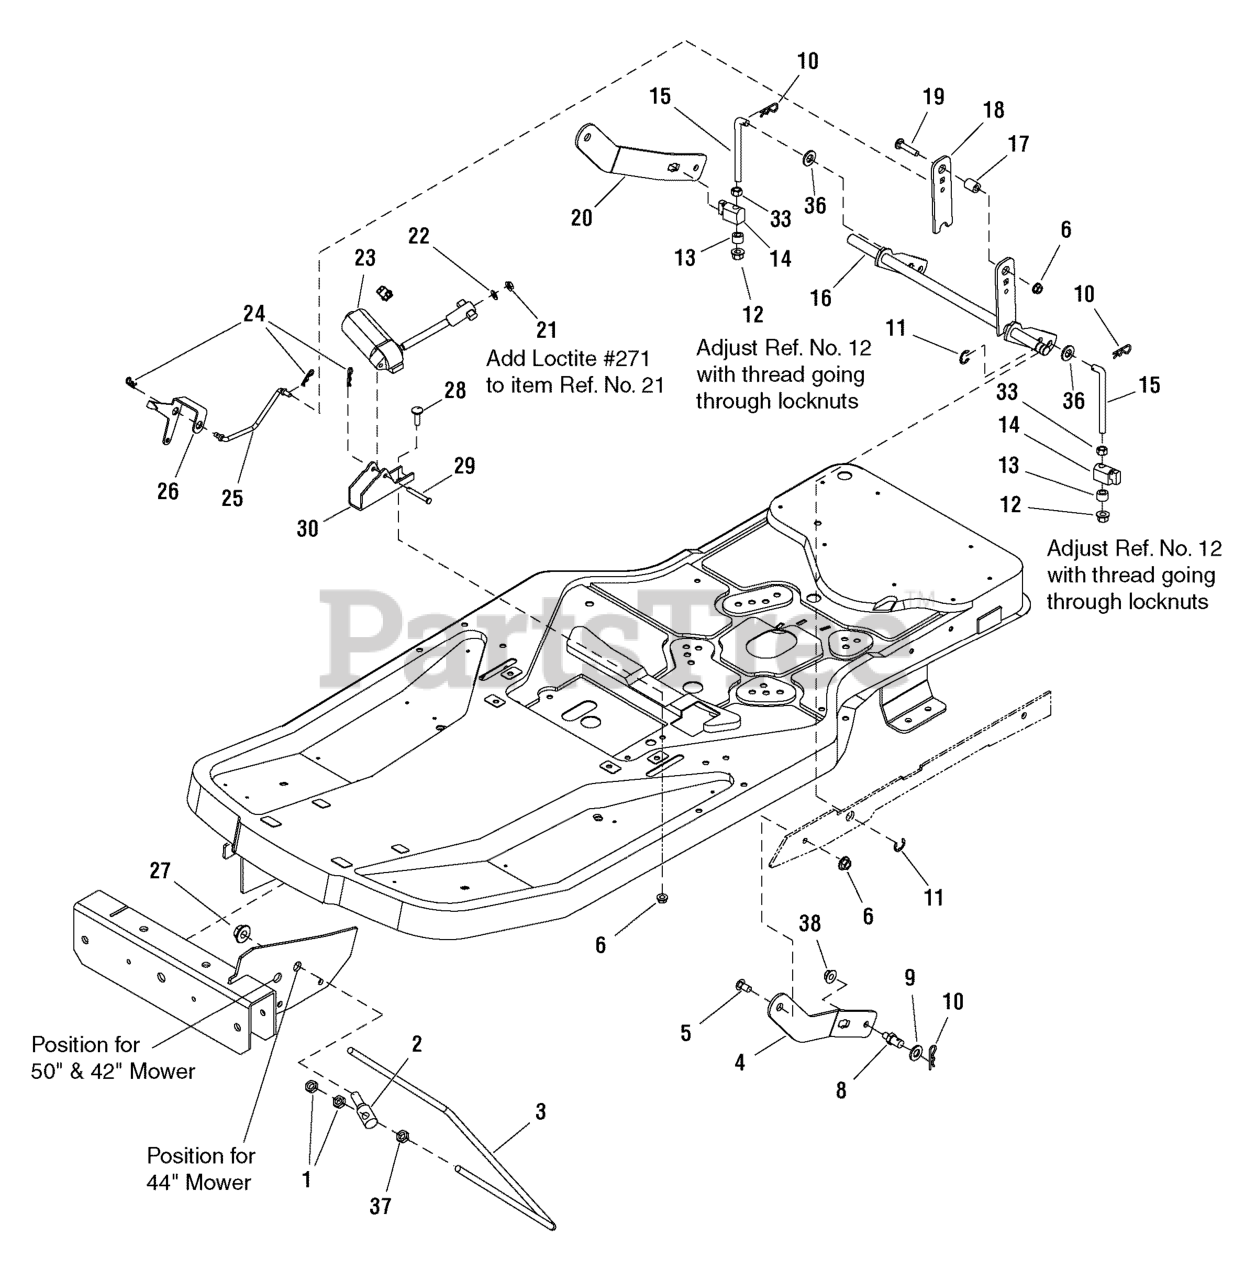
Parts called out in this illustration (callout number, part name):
1	NUT, Hex Jam, 7/16-14
2	TRUNNION
3	ROD, Bail
4	ARM, Mower Lift L.H.
5	BOLT, Shoulder
6	NUT, Hex Flange Whiz Lock, 5/16-18
8	PIN, Threaded Shoulder
9	WASHER, 1/2
10	CLIP, Hairpin
11	RING, Klipring, 5/8
12	NUT, Hex Flange Nylock, 3/8-16 ESNA
13	SPACER, Powdered Metal
14	TRUNNION, Powdered Metal
15	ROD, Mower Lift, 3.5 LG Thread
16	LIFT SHAFT ASSEMBLY
17	SPACER, Powdered Metal
18	ARM, Lift Trunnion
19	CARRIAGE BOLT, 5/16-18 x 1-1/2, G5
20	ARM, Mower Lift R.H.
21	NUT, Hex, 1/4-20 L.H. Thread
22	WASHER, 1/4
23	MOTOR, Mini Actuator
24	CLIP, Hairpin
25	ROD, Height of Cut Indicator
26	INDICATOR, Height of Cut
27	NUT, Hex Flange, Two-Way Lock, 1/2-13
28	BOLT, Carriage, Short Neck, 5/16-18 x 1
29	PIN, Shear
30	BRACKET, Electric Motor Mount
33	NUT, Hex, 3/8-16
36	WASHER, 3/8
37	NUT, Hex 7/16-14
38	NUT, Hex Flange Two-Way Lock, 3/8-16
